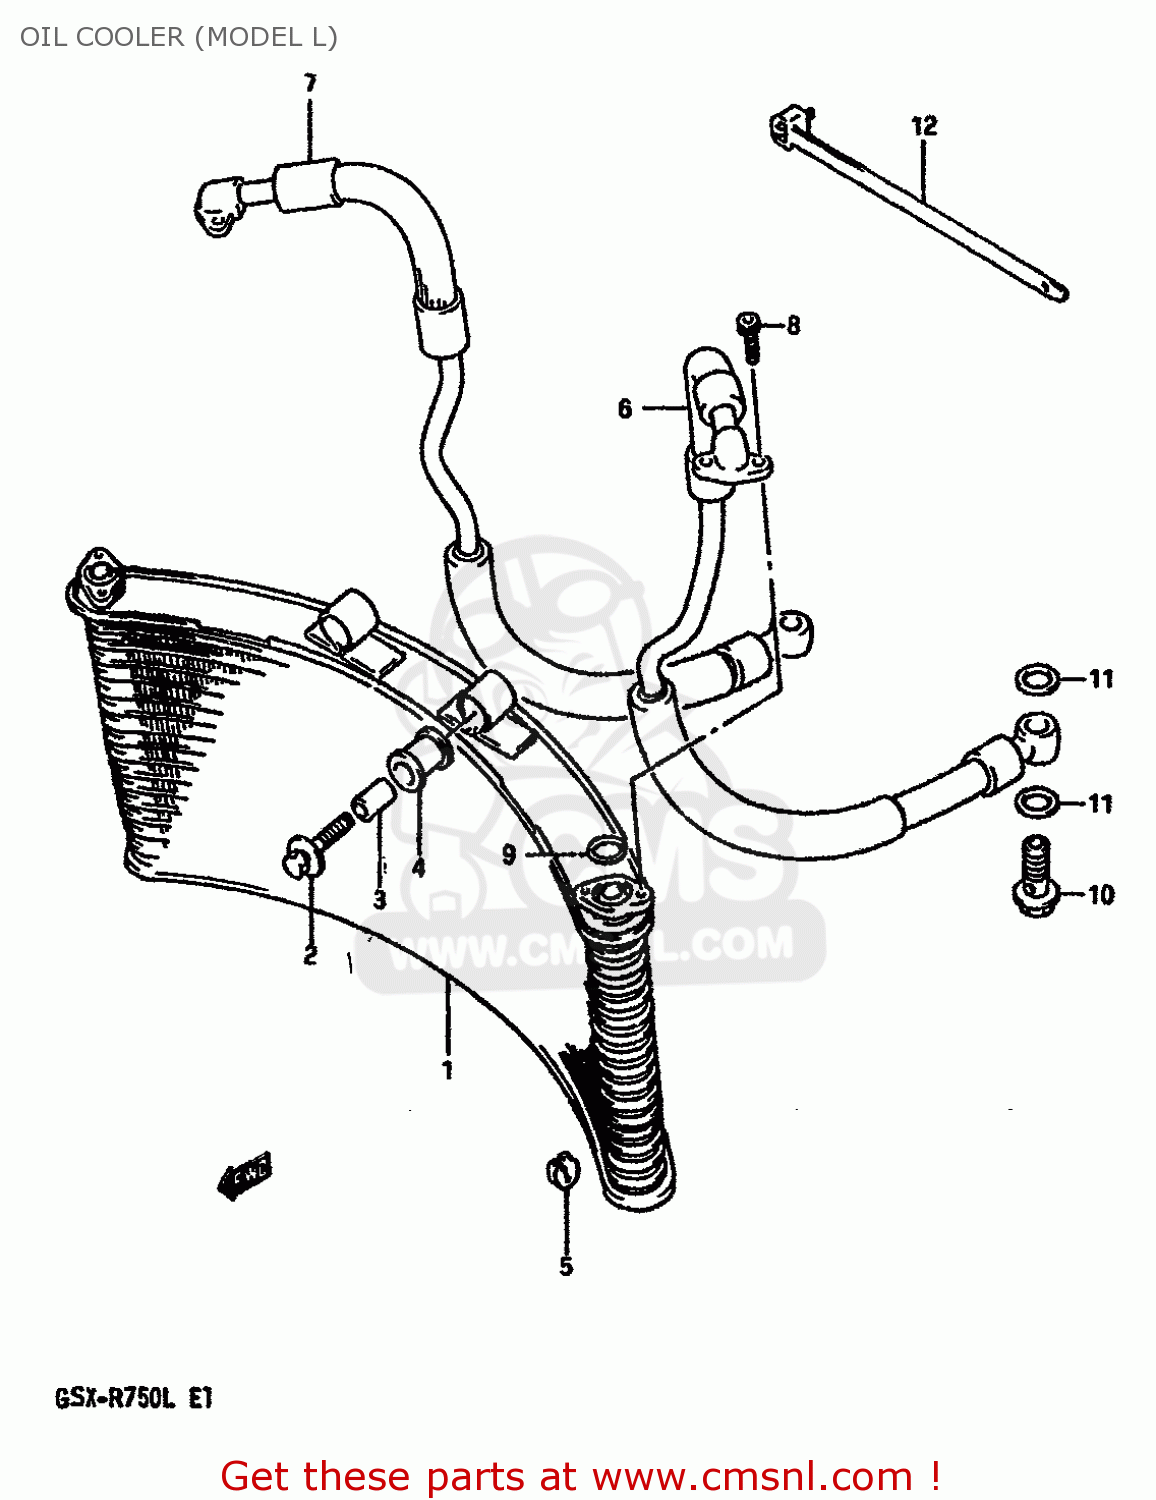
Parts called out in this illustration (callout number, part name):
1	COOLER ASSEMBLY,OIL
2	BOLT(8X40)
3	SPACER (8.8X12X24.5)
4	CUSHION,OIL COOLER NO.1
5	CUSHION,OIL COOLER NO.2
6	HOSE,OIL
7	HOSE,OIL
8	BOLT
9	O RING(D:2.4,ID:12.3)
10	BOLT UNION
11	GASKET(16X22X2) (NAS)
12	CLAMP
13	GASKET(16X22X2) (NAS)
14	CLAMP(L:250)
